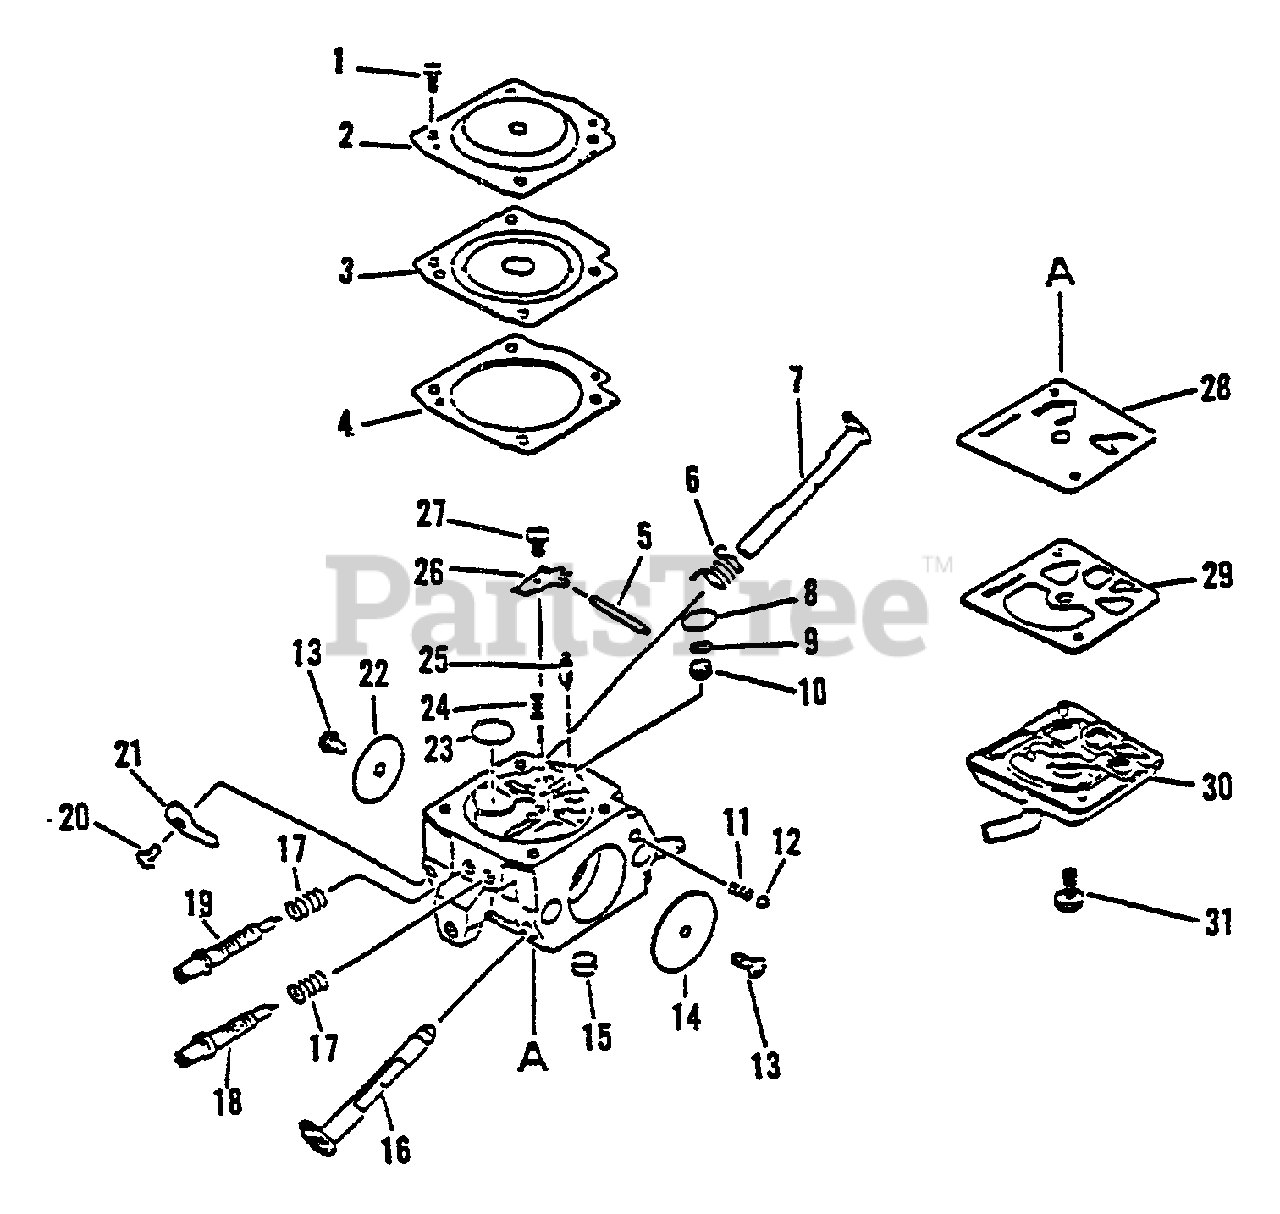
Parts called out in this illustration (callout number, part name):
1	SCREW
2	COVER, DIAPHRAGM
3	DIAPHRAGM
4	GASKET, METERING
5	PIN, METERING LEVER
6	SPRING, THROTTLE RETURN
7	SHAFT, THROTTLE
8	PLUG, WELCH
9	RING, RETAINING
10	STRAINER
11	SPRING, THROTTLE FRICTION
12	BALL, CHOKE
14	VALVE, CHOKE
16	SHAFT, CHOKE
17	SPRING
18	NEEDLE, HIGH SPEED
19	NEEDLE, IDLE
21	LEVER, THROTTLE
22	VALVE, THROTTLE
23	PLUG, WELCH
24	SPRING
25	VALVE, NEEDLE
26	LEVER, METERING
27	SCREW
30	COVER, PUMP
